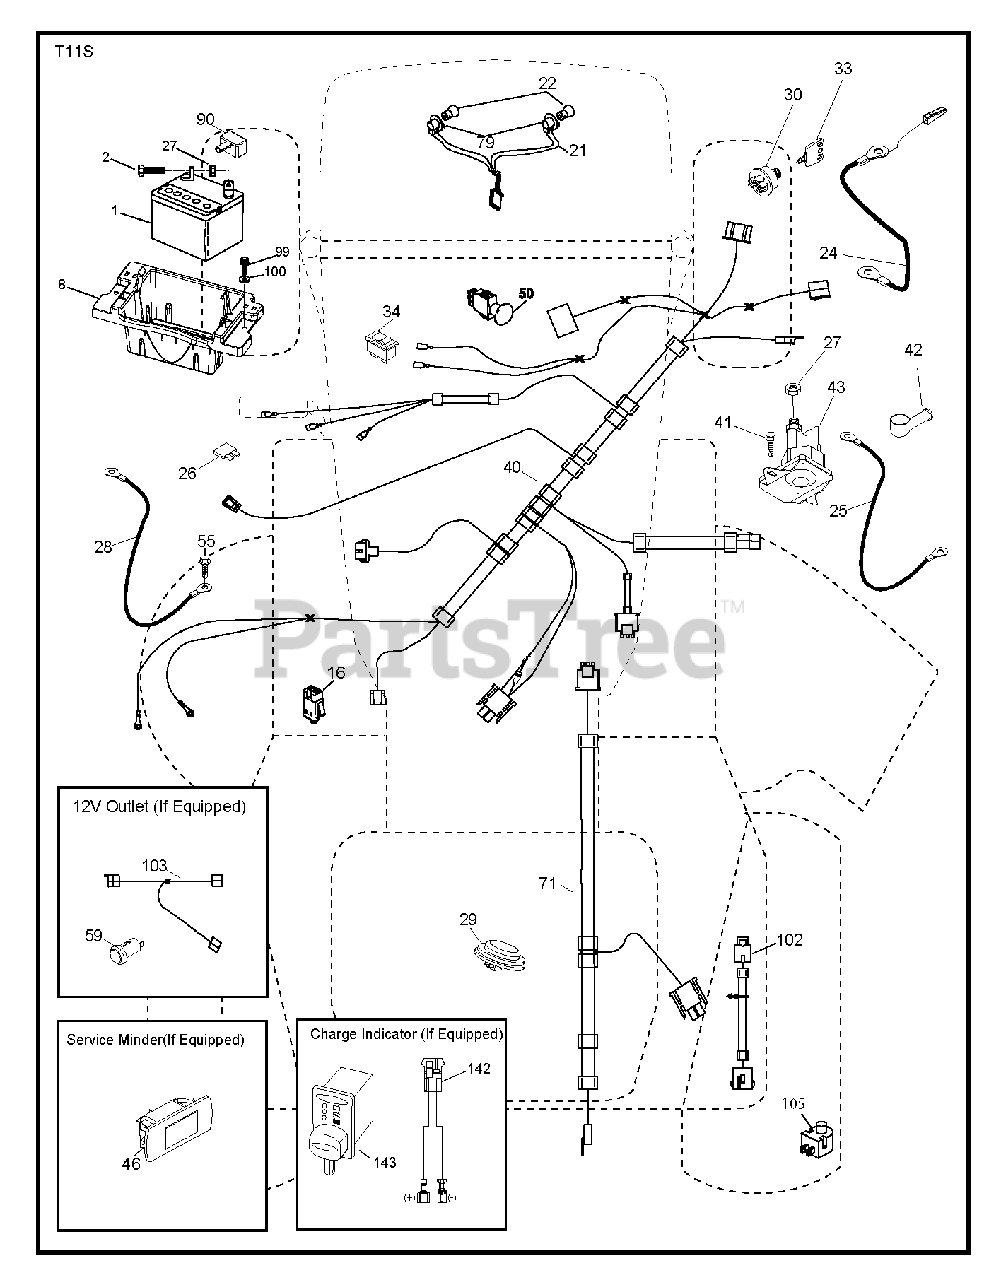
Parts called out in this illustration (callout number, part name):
1	Battery, Dry 30 Amp
2	BOLT.HEX.1/4.X.3/4.DICHROMATE
8	TRAY.ASM.BATTERY.FRT.TEX.CARB
16	SWITCH INTERLOOK PUSH-IN
21	HARNESS.LIGHT W/4152J BULBS
24	CABLE.FRBATT.W/WIRE.8GA.8
25	CABLE.STARTER.6G.BL/RED.17.5
26	FUSE 20AMP
27	NUT
28	CABLE GROUND 6 GA 21" 90T BLK
29	SWITCH.SEAT.DELTA.OPC.
30	SWITCH.IGN.DELTA.W.LGH.ROS
33	KEY.CHAIN.BLISTER.PACK.GEN.USA
40	HARNESS HARNESS..DASH.ING.ELEC
41	SCREW
42	TERMINAL COVER
43	SOLENOID.STARTER.BRASS.PLUNGER
50	SWITCH.PTO.8TERMINAL.STD.BLK
55	SCREW 5/16"
71	HARNESS-CHASSIS SUB
79	BULB HOLDER ASM.
90	COVER.TERMINAL.BATTERY
99	SCREW HEXWSHR 1/4-20X3/4
102	HARNESS PIGTAIL PCH TEX ROS
105	REVERSE SWITCH
